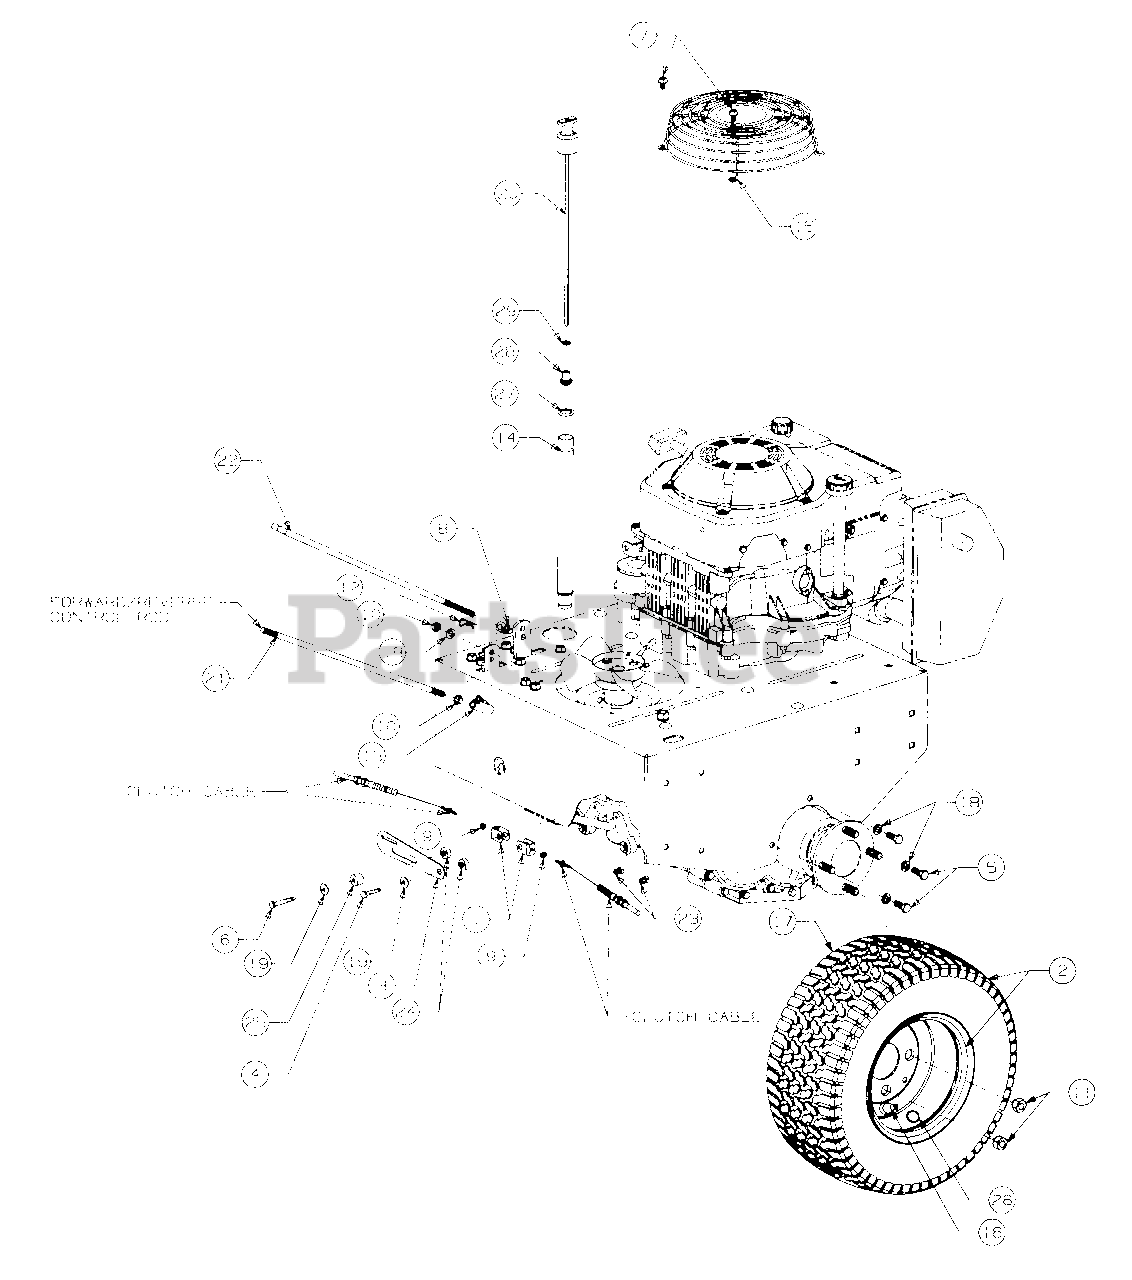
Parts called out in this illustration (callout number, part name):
1	U-Clevis, Clutch Cable
2	Wheel & Tire Assy, Complete, 16 X 6.50-8 (Include Ref No. 26)
3	Plate, Parking Brake Switch Mount
4	Screw, Hex Cap, 1/4-28 X 1.25 Lg GR5
5	Screw, Hex Cap, 3/8-16 X 1.0 Lg GR5
6	Screw, Hex Cap, 1/4-28 X 1.75 Lg GR5
7	Screw, HexWash Hd Tapp, 5/16-18 X .50 Lg
8	Ferrule, 3/8-24 X .37 Dia
9	Nut, Hex Jam, #10-32
10	Nut, Hex Jam, 3/8-24 GR5
11	Nut, Lug, 1/2-20
13	Ball Joint, 3/8-24
14	Tube, Oil Fill
15	Guard, Fan Cover
16	Valve, Tubeless Air
17	Tire, Turf Chief, 16 X 6.50-8
18	Washer, Lock, 3/8
19	Washer, Bell, .265 X .75 X .062 Thk
21	Rod, F/R Control
22	Rod, PTO Control
23	Nut, Clevis, Spacer, 1/4-28
24	Spacer, Clevis
25	Spacer, Switch Engagement
26	Label, Inflation
28	Seal, Rubber
29	Washer, Plain, 5/16
